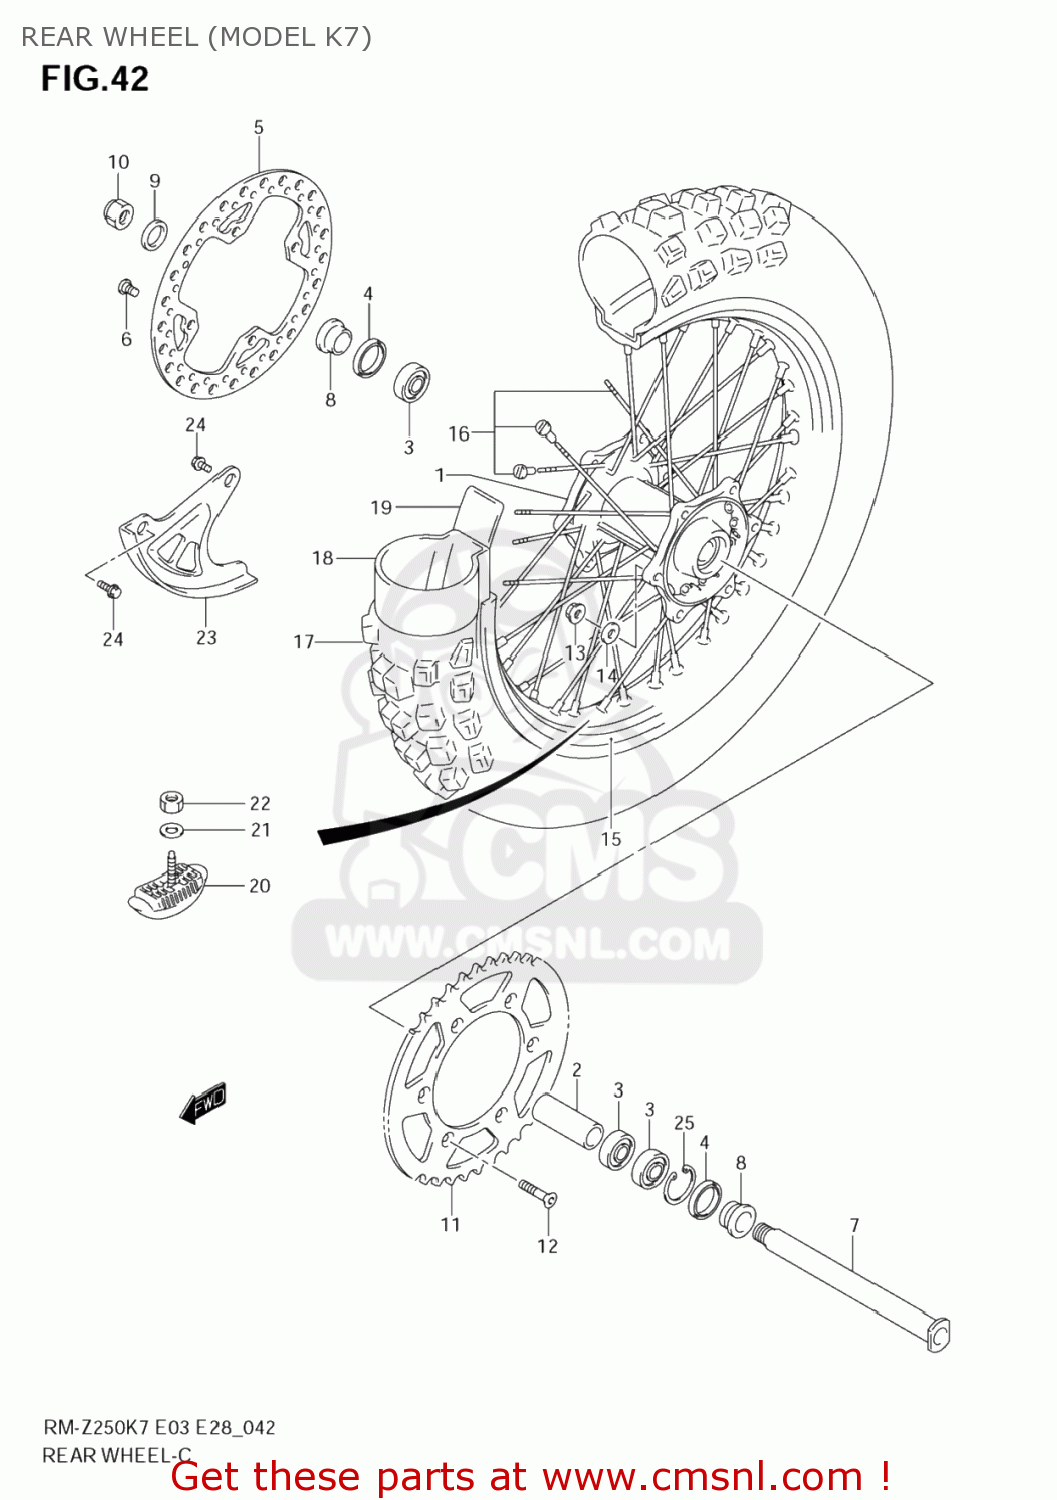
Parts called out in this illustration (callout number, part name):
1	HUB,RR
2	SPACER,RR HUB BEARING
3	BEARING(25X42X9)
4	SEAL,OIL(32X43X7)
5	DISC,RR BRAKE
6	SCREW(8X15)
7	AXLE,REAR
8	SPACER,REAR AX
9	WASHER(22X35X2)
10	NUT
11	SPROCKET,RR(NT:48)
12	BOLT(8X28)
13	NUT
14	WASHER(8.5X16X1.2)
15	RIM,RR WHEEL(19X1.85 AL)(WHT)
16	SPOKE SET,RR WHEEL
17	TIRE,RR(100/90 19)
18	TUBE
19	PROTECTOR,WHL INR TUBE
20	STOPPER,BEAD(1.85)
21	WASHER
22	NUT
23	COVER,REAR DIS
24	BOLT(6X12)
25	CIRCLIP
